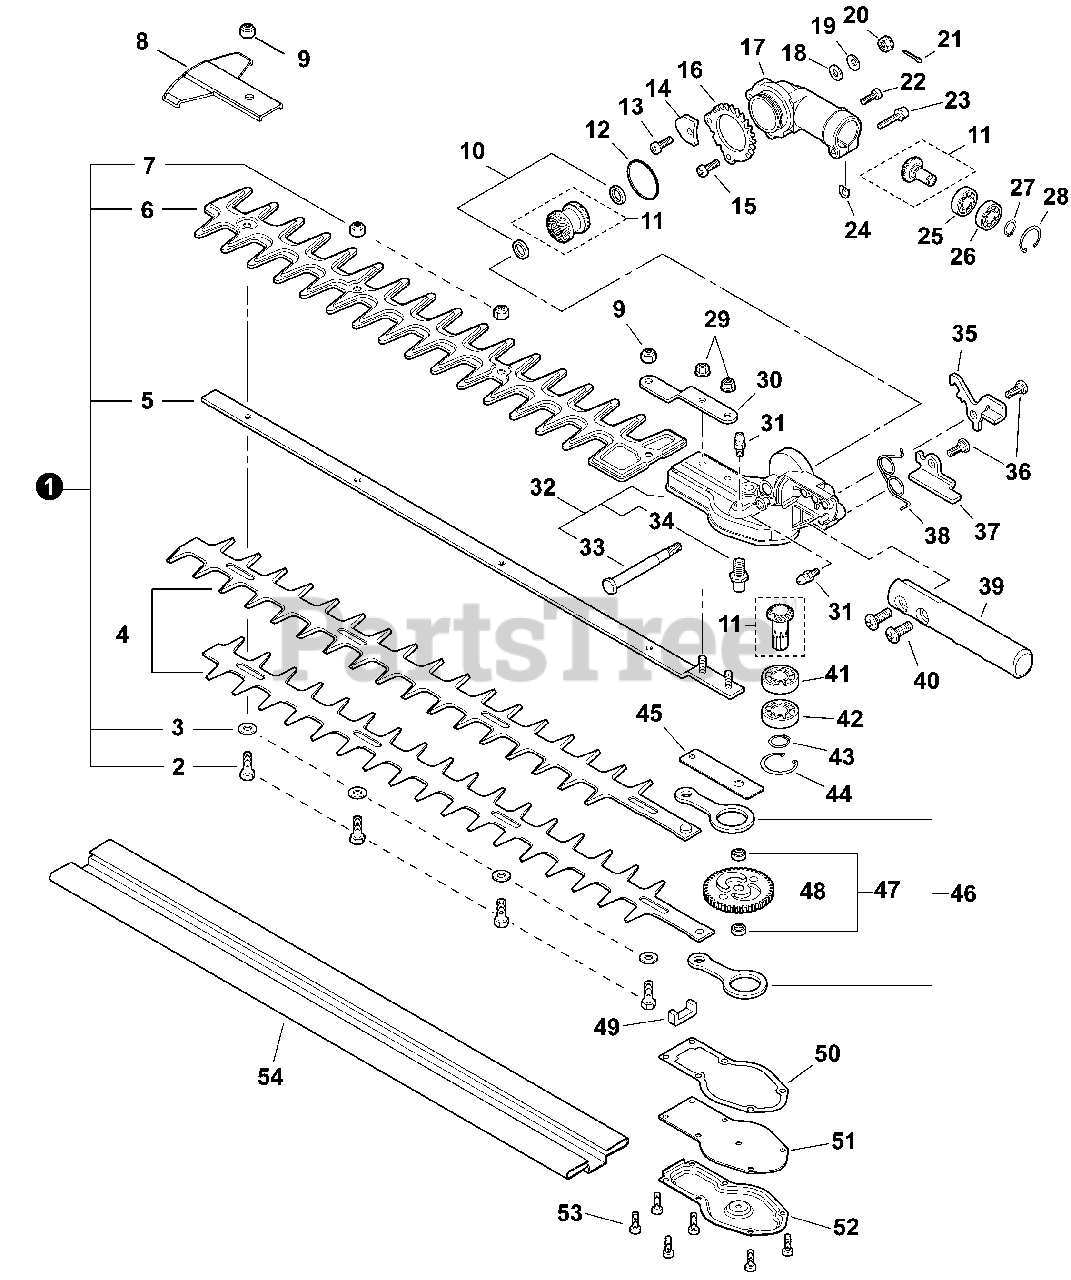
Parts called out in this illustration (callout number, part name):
1	CUTTER ASSY, 22"
2	BOLT M6×20
3	WASHER M6
4	CUTTER 22"
5	GUIDE BAR 22"
6	GUARD, CUTTER BLADE
8	GUARD, TIP
10	COLLAR 16×10×L= 2
11	GEAR SET
13	SCREW M5×16
14	PLATE, STOPPER
15	BOLT 5×12
16	RING, LOCKING
17	HOUSING, UPPER GEAR CASE
18	WASHER 6.5×13×1
19	WASHER, CONE M6
21	PIN, COTTER 1.6×15
22	BOLT 5×12
23	BOLT M5×25
24	D-WASHER
25	BEARING, BALL 609
26	BEARING, BALL 609ZZ
27	RING, SNAP 9
28	RING, SNAP 24
29	NUT, FLANGE M5
30	BRACKET, CUTTER
31	FITTING, GREASE
32	GEAR CASE HOUSING ASSY
34	MAINSHAFT
35	LEVER, LOCK
36	PIN, RATCHET M6
37	RELEASE, LOCK
38	SPRING, TORSION
39	LEVER, ADJUSTMENT
40	SCREW, TRUSS M6×20
41	BEARING, BALL 6001
42	BEARING, BALL 6001ZZ
43	RING, SNAP 12
44	RING, SNAP 28
45	PLATE, GUIDE
47	SPACER 11×8×3.4
48	GEAR, CAM
49	PACKING, FELT
50	GASKET, GEAR CASE
52	COVER, GEAR CASE
53	BOLT 4×10
54	SCABBARD
